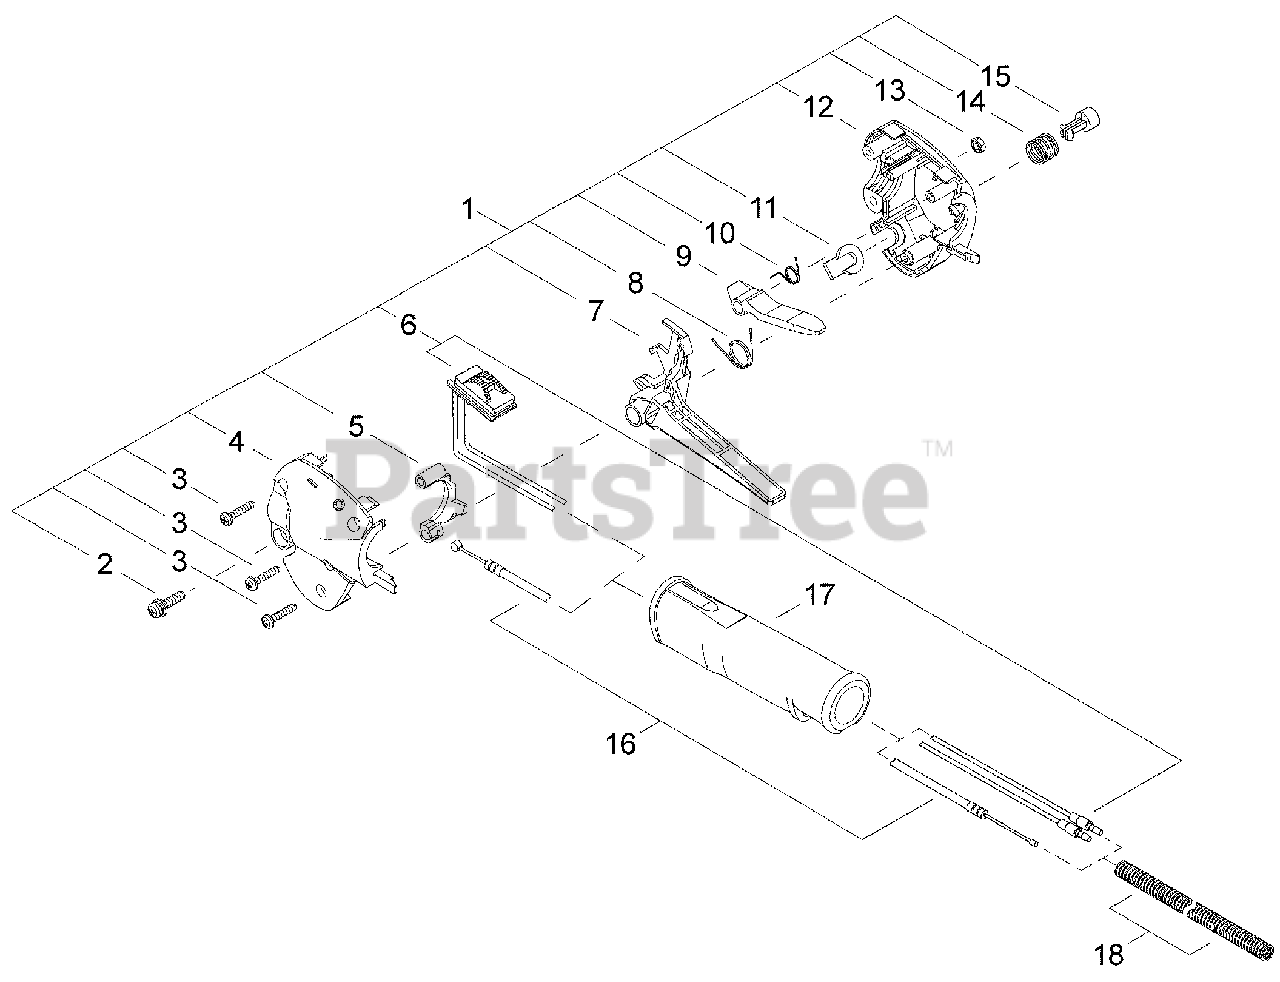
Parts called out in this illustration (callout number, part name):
1	THROTTLE CONTROL ASSY
2	SCREW M5×20
3	SCREW, TAPPING M4×20
4	CONTROL HANDLE - LEFT
5	LOCKOUT, THROTTLE
6	SWITCH, ON-OFF
7	TRIGGER, THROTTLE
8	SPRING, THROTTLE RETURN
9	LEVER, THROTTLE LOCKOUT
10	SPRING, THROTTLE LOCKOUT
11	PLUG
12	CONTROL HANDLE - RIGHT
13	NUT M5
14	SPRING, COMPRESSION
15	BUTTON, THROTTLE LOCK
16	CABLE, THROTTLE
17	GRIP, REAR
18	TUBE, PLASTIC PROTECTIVE
